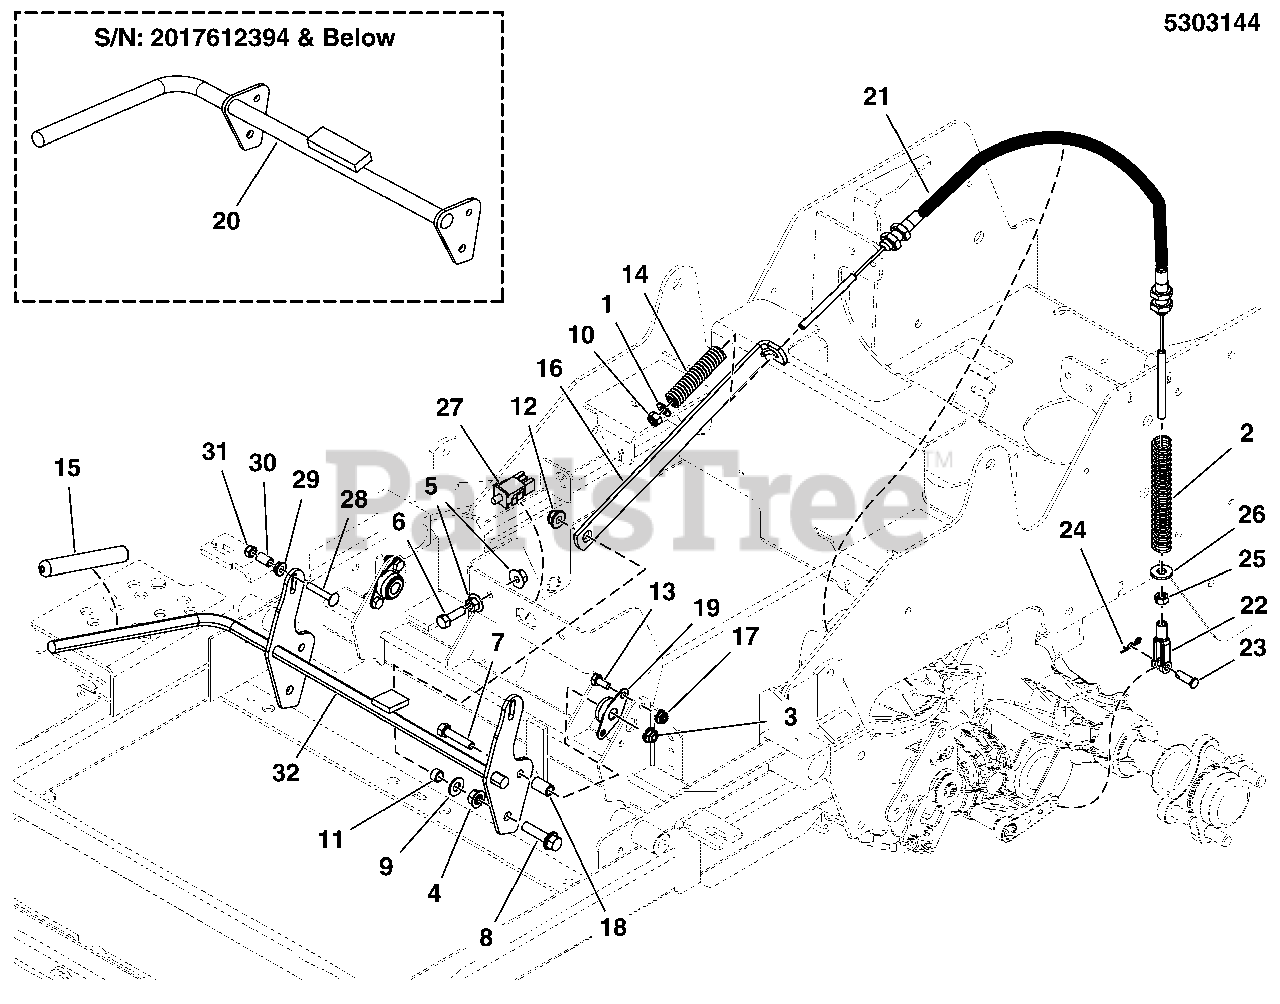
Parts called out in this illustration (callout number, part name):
1	WASHER, 5/16 SAE
2	SPRING, COMPRESSION, 5-1/2
3	NUT, 5/16-18 HEX NYLOCK FLANGE
4	NUT, 3/8-16 HEX SERRATED FLANGE
5	NUT, 5/16-18 HEX SERRATED FLANGE (LARGE)
6	BOLT, 5/16-18 X 1-1/8 GD5
7	BOLT, 5/16-18 X 1-1/2 GD5 YZ
8	BOLT, 3/8-16 x 1-1/2, FLANGE, GD 5, CZ
9	WASHER, 3/8 SAE
10	NUT, 5/16-24 HEX NYLON LOCK
11	SPACER, .38 X .50 X .27, CZ
12	NUT, 3/8-16 HEX NYLOCK FLANGE
13	BOLT,1/4-20X5/8
14	SPRING-COMP, .496ID X 3.00LG X .112WR
15	GRIP, FOAM, .475 X 4.35 X .095
16	LINK, BRAKE LOCK, IS700 - BLK
17	NUT, 1/4-20 HEX NYLOCK FLANGE (5025391)
18	SPACER, .32 X .50 X .83, CZ
19	BEARING, 1/2 FLANGED, PLASTIC BALL
20	WELD, BRAKE SHAFT, IS600 - BLK
21	CABLE, PARKING BRAKE, 31" (787.9 MM)
22	CLEVIS, 5/16-18, 5/16 PIN HOLE, STEEL
23	PIN-CLEVIS, 5/16 X 1 YZ
24	PIN, HAIR, .0585 X 1-1/8, 1/4 EYE, YZ
25	NUT, 5/16-18 HEX
26	WASHER, 5/16 USS
27	SWITCH, DP NO/NC SNAP-IN
28	BOLT, 1/4-20 X 1.500, GR5, SQ, ZINC/CLEAR
29	NUT, 1/4-20 HEX SERR. FLANGE
30	SPACER, .52 X .38 X .63, CZ
31	NUT, 1/4-20 HEX NYLON LOCK
32	WELD, BRAKE SHAFT - BLK
